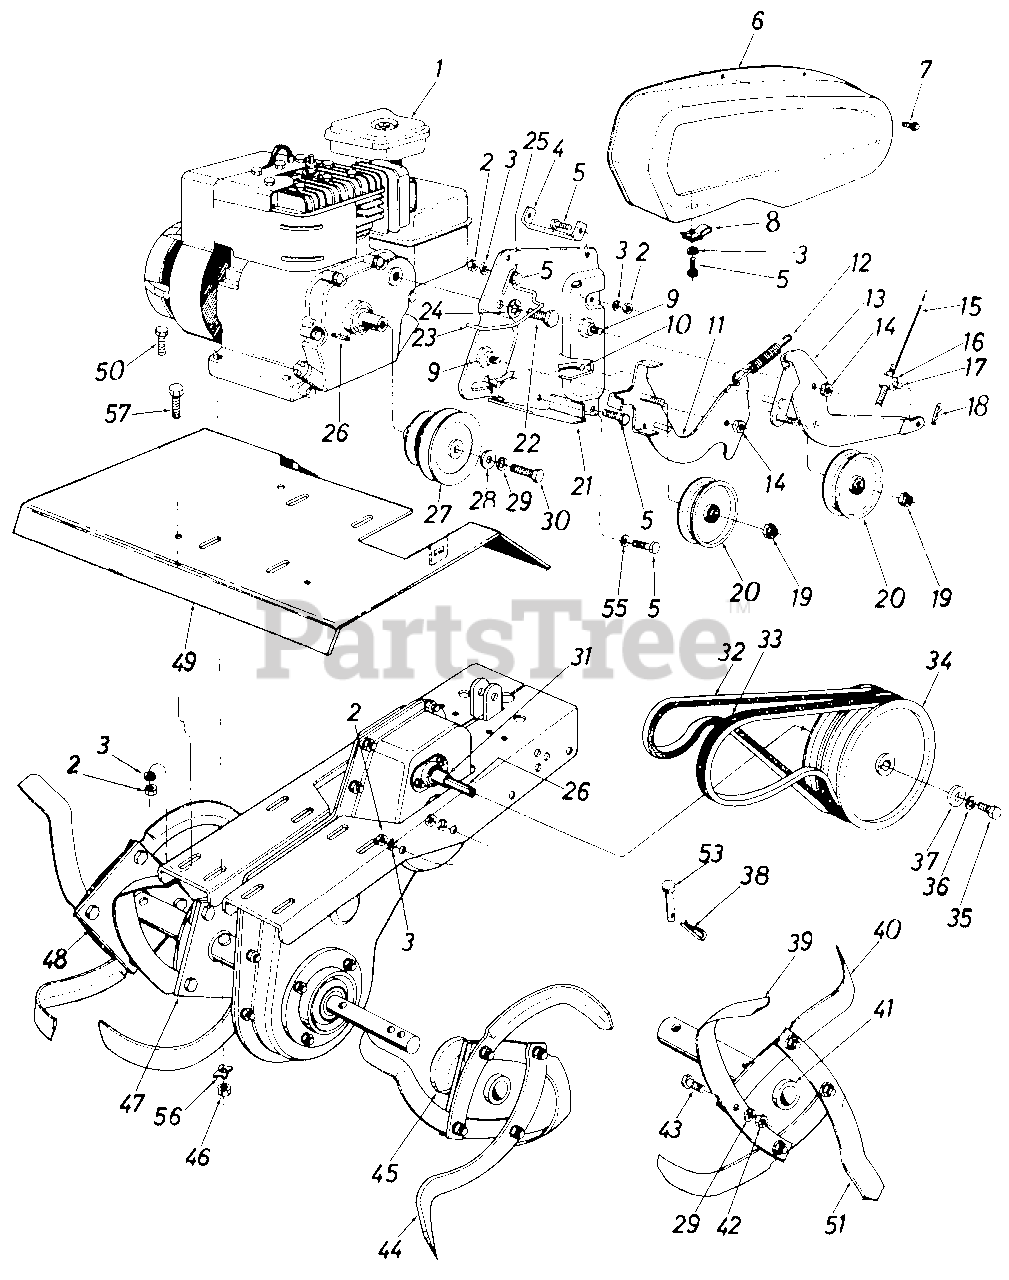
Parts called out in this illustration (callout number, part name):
1	Engine
2	Hex Nut 1/4-20 Thd.
3	L-Wash. 1/4" Scr.
4	Support Bracket
5	Hex Scr. 1/4-20 x .75" Lg.
8	"U"-Type Speed Nut
9	Shoulder Bolt .625 Dia. x .170" Lg.
10	Control Rod
11	Reverse Idler Brkt. Ass'y.
12	Spring - Idler Brkt.
13	Forward Idler Brkt. Ass'y.
14	Hex Cent. L-Nut 3/8-16 Thd.
15	Clutch Control Rod
16	Speed Nut 3/8-24 Thd.
18	Inter. Cotter Pin 1/2" Dia.
19	Hex Jam Nut 3/8-24 Thd.
20	Fl-Idler w/Flanges 3.12 O.D. x .75
21	Clutch Mounting Plate
22	Hex Bolt 1/2-20 x .75 Spec.
23	Belt Guard Rod
24	Internal L-Wash. 1/4" I.D.
25	Fl-Wash. 1/4" I.D.
26	Sq. Key 3/16 x 1.50" Lg.
27	Engine Pulley
28	Fl-Wash. 3/8" I.D. x 1.00" O.D.
29	L-Wash. 3/8" I.D.
30	Hex Bolt 3/8-24 x 1.25" Lg.
31	Spacer .635 I.D. x .88 O.D. x 1.035 Lg.
32	"V"-Belt 1/2" x 41" Lg. Reverse
33	"V"-Belt 1/2" x 37" Lg. Forward
34	Chain Case Pulley 6.0" Dia.
35	Hex Bolt 5/16-18 x 1.25 Lg. Spec.
36	Shake-Proof Wash.
37	Fl-Wash. 5/16" I.D. x 1.120 O.D.
38	Internal Cotter Pin 1/2" Dia.
43	Hex Bolt 3/8-24 x 1.25" Lg.
44	Inner Tine Ass'y. Comp. - L.H.
45	Inner Tine Adapter Ass'y.
46	Hex Nut 5/16-18 Thd.
47	Inner Tine Ass'y. Comp. - R.H.
48	Outer Tine Ass'y. Comp. - R.H.
49	Tine Shield
50	Hex Scr. 5/16-18 x 1.50" Lg.
51	Outer Tine Ass'y. Comp. - L.H.
53	Clevis Pin
55	Bell-Wash.
56	Shake-Proof Wash.
57	Hex Scr. 1/4-20 x .75" Lg.
